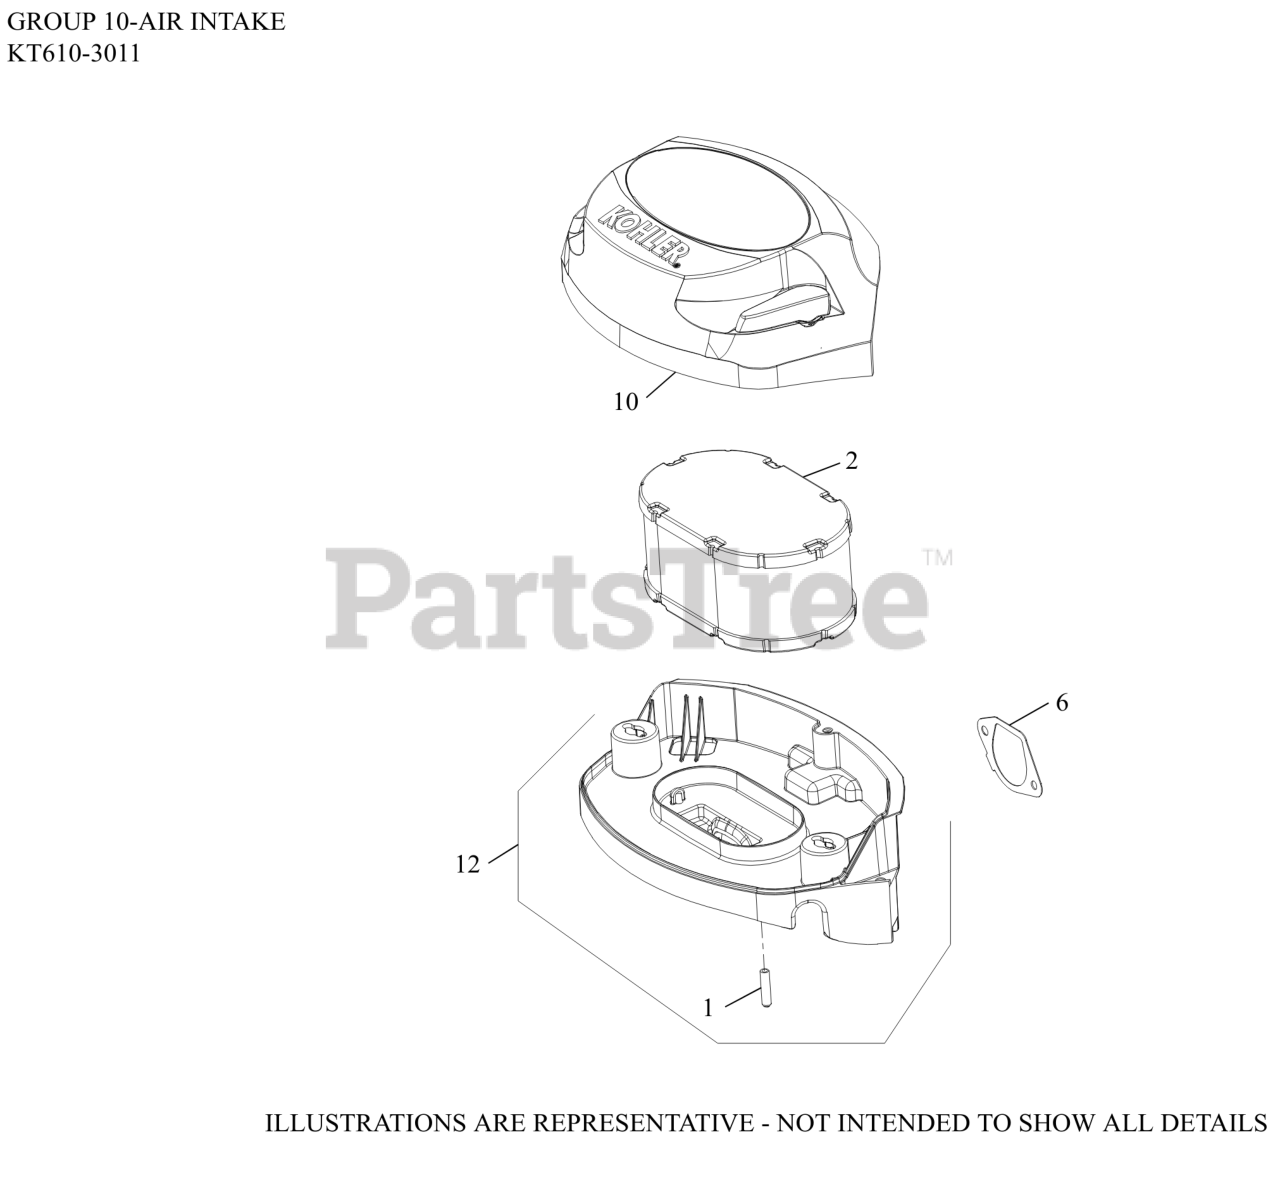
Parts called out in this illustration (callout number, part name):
1	CAP, MASKING
2	ELEMENT, AIR FILTER
6	GASKET, AIR CLEANER BASE
10	COVER ASSY, AIR CLEANER
12	BASE ASSY, AIR CLEANER
